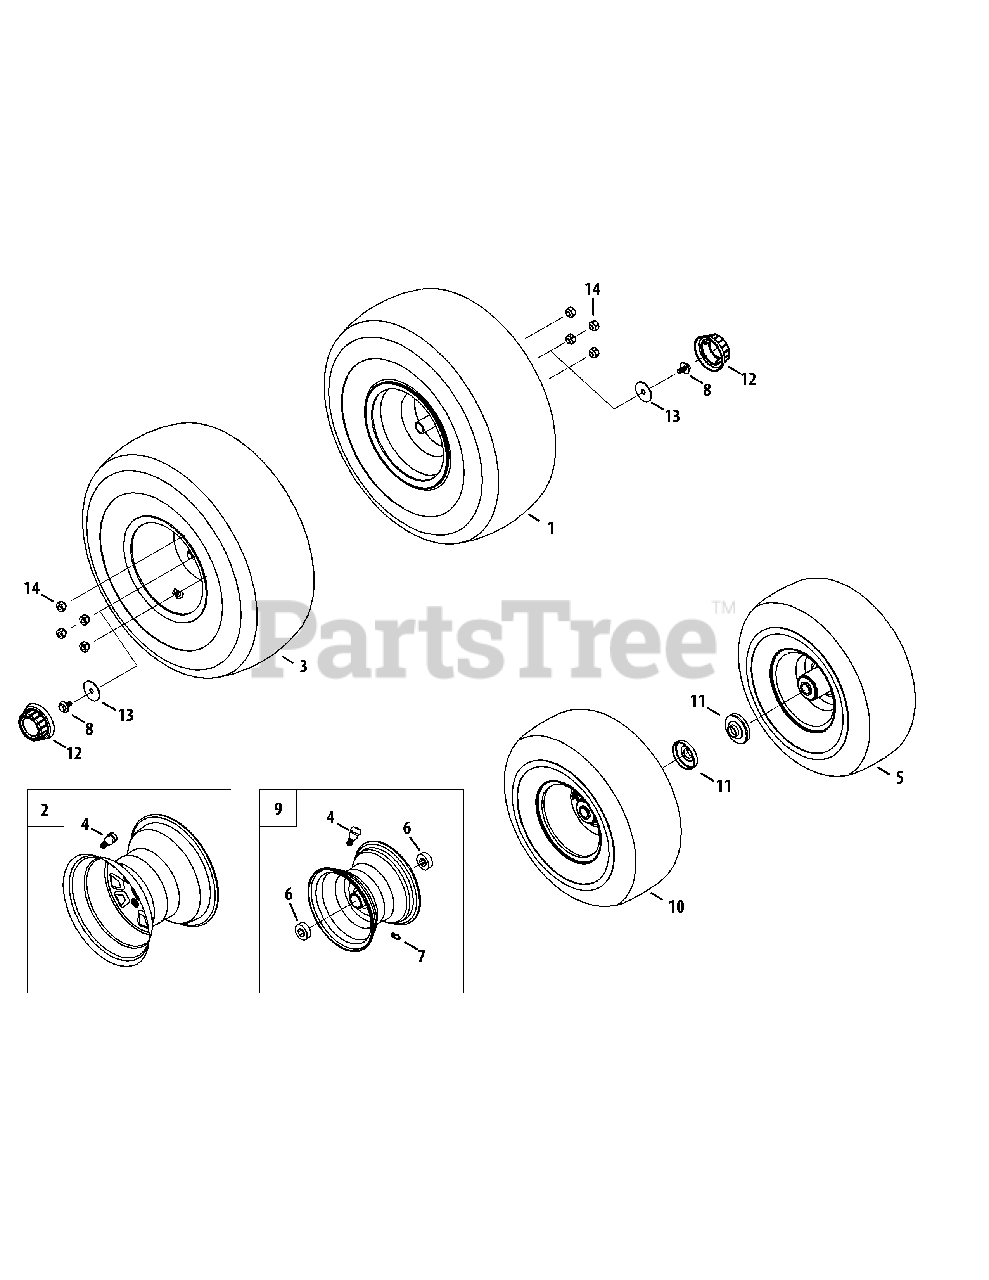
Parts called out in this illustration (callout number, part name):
1	Wheel, Complete, 20 x 8 x 8
2	Rim Ass’y, 8.0 x 7.0 x .750 ID
3	Tire, 20 x 8 x 8 Mult Trac
4	Valve, Tubeless Air
5	Wheel, Complete, 15 x 6 x 6
6	Bearing, Ball, .750 ID
7	Grease Fitting
8	Screw, 5/16-24 x .850
9	Rim Ass’y, 6.0 x 4.5
11	Bearing Cover
13	Flat Washer, .406 x 1.92 x .060
14	Lug Nut 7/16-14 (GX)
